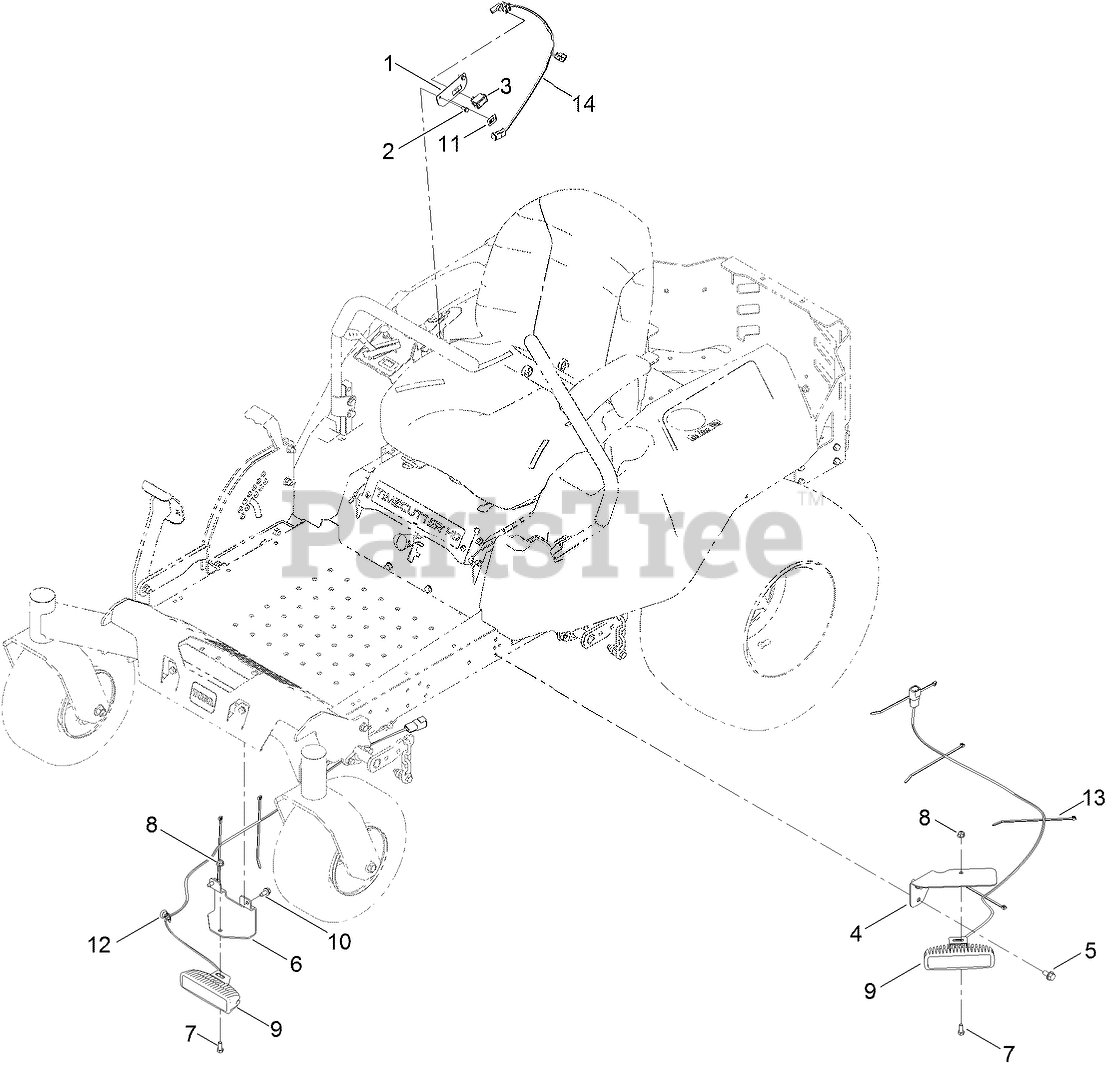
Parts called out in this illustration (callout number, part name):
1	BRACKET-SWITCH, LIGHT
2	SCREW-TAPTITE
3	SWITCH-ROCKER
4	BRACKET-LIGHT, SIDE
5	SCREW-HWH
6	BRACKET-LIGHT
7	SCREW-HH
8	NUT-HF, NI
9	LIGHT-LED
10	SCREW-HWHTF
11	DECAL-SWITCH, LIGHT
12	MOUNT-TIE WRAP, MAGNETIC
13	TIE-CABLE
14	HARNESS-WIRE
